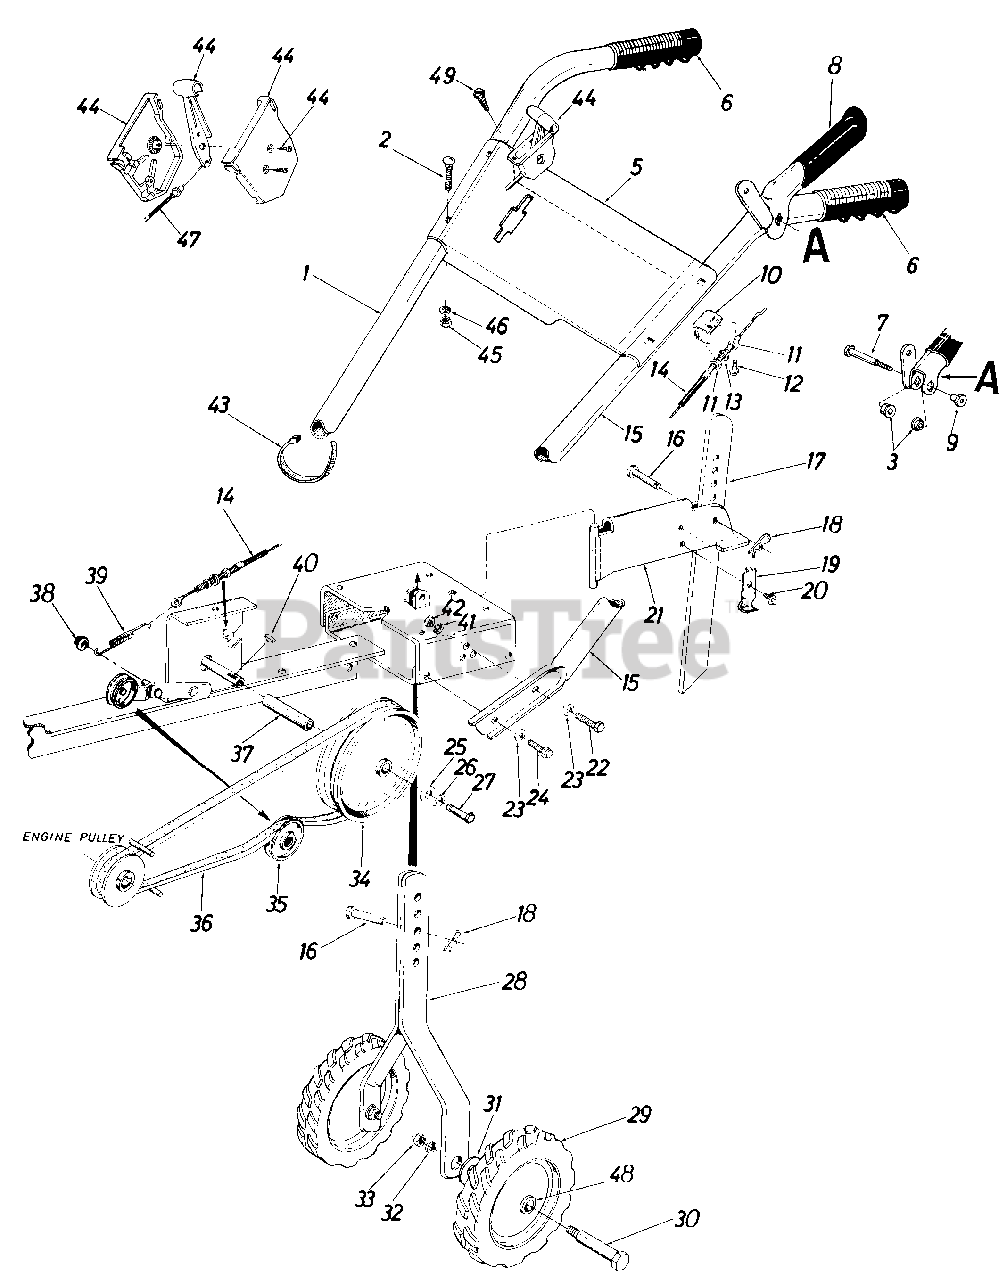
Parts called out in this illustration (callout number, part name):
1	Handle R.H.
2	Carriage Bolt 5/16-18 x 1.75" Lg.
3	Hex Flange Plastic Brg.
5	Handle Panel
6	Grip
7	Shld. Bolt .374" Dia. x 1.375" Lg.
8	Clutch Grip Ass'y.
9	Shld. Nut 1/4-20 Thd.
10	Cable Support Brkt.
11	Hex Jam Nut 5/16-24 Thd.
12	Hex Wash. Hd. Self-Tap Scr. 1/4-20 x .50" Lg.
13	L-Wash. 5/16" I.D.
14	Clutch Control Cable
15	Handle L.H.
16	Clevis Pin
17	Depth Bar
18	Hairpin Cotter
19	Depth Bar Spring
20	Hex Wash. Hd. Self-Tap Scr. 1/4-20 x .50" Lg.
21	Tailpiece Ass'y.
22	Hex Scr. 3/8-16 x 1.00" Lg.
23	Belleville Wash. 3/8" I.D.
24	Hex Wash. Hd. Self-Tap Scr. 318-24 x 718" Lg.
25	Fl-Wash. .25" I.D. x .930" O.D. x .120" Thk.
26	L-Wash. 1/4" I.D.
27	Hex Scr. 1/4-28 x .75" Lg.
28	Wheel Bracket Ass'y.
29	Wheel Ass'y. 10 x 1.75
30	Shld. Bolt
31	Belleville Washer 1/2" I.D.
32	L-Wash. 1/2" Scr.
33	Hex Nut 1/2-20 Thd.
34	Pulley 6.00" O.D.
35	Idler Pulley
36	V-Belt 1/2" Pitch x 39"
37	Spacer
38	Cap Speed Nut
39	Extension Spring
40	Hi-Pro Key
41	L-Wash. 3/8" Scr.
42	Hex L-Nut 3/8-16 Thd.
43	Cable Ties
44	Throttle Control Box
45	Hex Nut 5/16-18 Thd.
46	L-Wash. 5/16" Scr.
47	Throttle Control Wire 35"
48	Bearing
49	Self-Tapping Scr. #10 x .50" Lg.
